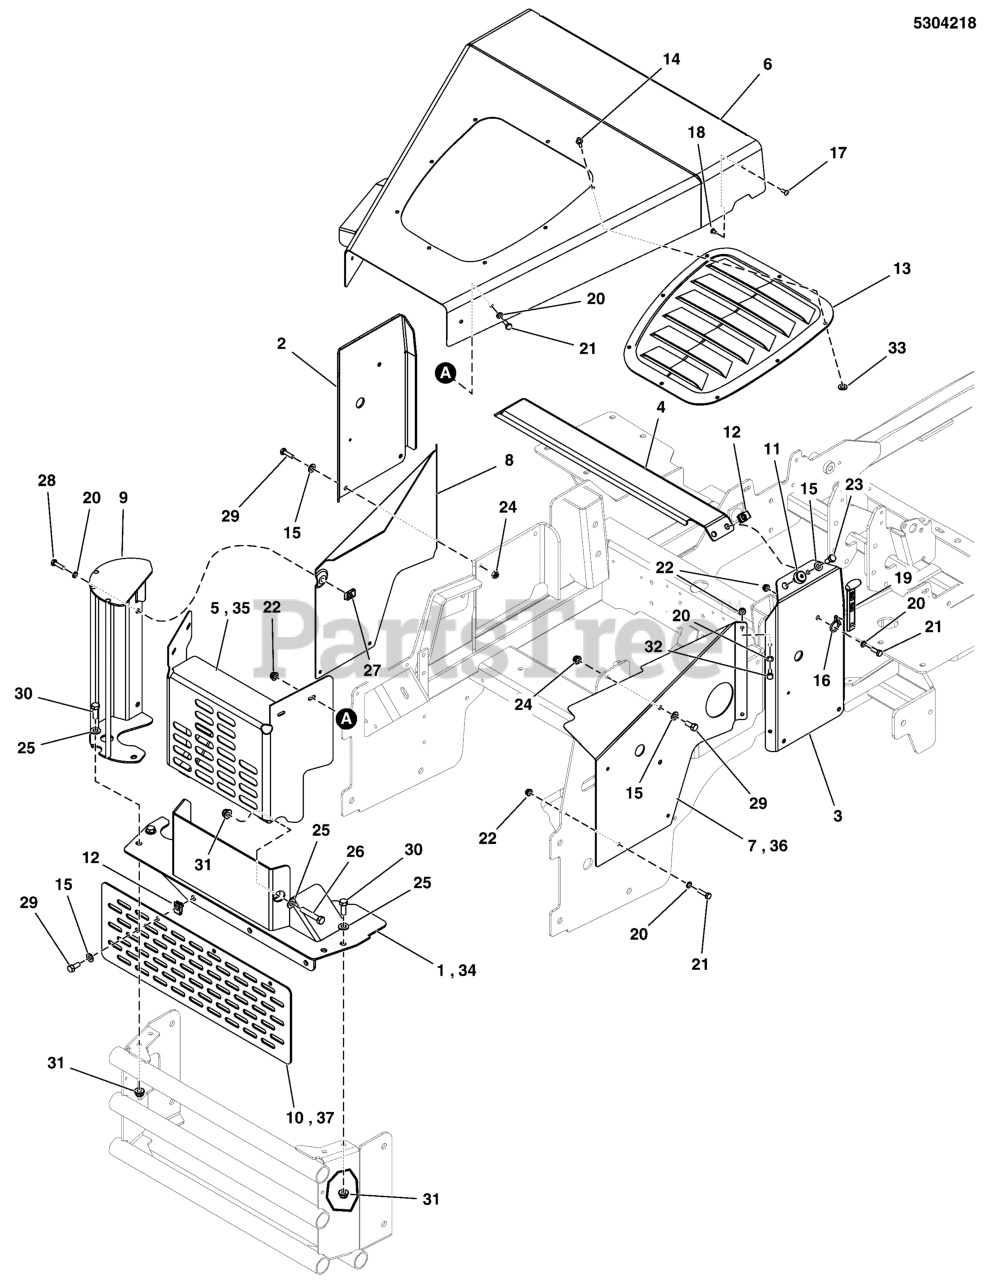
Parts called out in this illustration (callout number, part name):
1	WELD, HINGE MOUNT - RED
2	PLATE, LH HOOD SUPPORT, IS2600 - RED
3	PLATE, RH HOOD SUPPORT, IS2600 - RED
4	PLATE, CENTER HOOD SUPPORT, IS2600 - RED
5	WELD, ENGINE COVER, REAR - RED
6	WELD, HOOD, IS2600Z - RED
7	COVER, ENGINE SIDE, RH - RED
8	COVER, ENGINE SIDE, LH - RED
9	WELD, MUFFLER GUARD, IS2600Z
10	GUARD, REAR BELT
11	MNT, VBRTN, RBBR
12	BODY CLIP, 5/16-18-7GA MATERIAL
13	SCOOP, HOOD, OUTFRONT MOWER
14	POP RIVET, 3/16" X .575"(.251-.375GP)BLK
15	WASHER, 5/16" SAE
16	HOOK-.125DIA WIRE GR CAT STRAP YELLOW
17	BINDING POST #8-32X.500 INT THR BLK
18	SCREW-HEX SERR FLNG LK # 8-32X0.375 YEL
19	STRAP, HOOD, BLACK RUBBER
20	WASHER, 1/4 SAE
21	BOLT, 1/4-20 X 3/4 GD5 CZ
22	NUT, 1/4-20 HEX NYLOCK FLANGE
23	BOLT, 5/16-18 X 1 GD5 CZ
24	NUT, 5/16-18 HEX NYLOCK FLANGE
25	WASHER, 3/8 SAE
26	BOLT, 3/8-16 X 2, GD5, CZ
27	BODY CLIP, 1/4-20 X 1/2 DEEP
28	BOLT, 1/4-20 X 1" GD5 CZ
29	BOLT, 5/16-18 X 3/4 GD5
30	BOLT, 3/8-16 X 1" GD5 CZ
31	NUT, 3/8-16 HEX NYLOCK FLANGE
32	HHCS, 1/4-20 X 0.625, GR5, ZINC/CLEAR
33	WASHER, #10 SAE
34	WELD, HINGE MOUNT - RED
35	WELD, ENGINECOVER, REAR - RED
36	COVER, ENGINE SIDE, RH - RED
37	PLATE, GUARD, BUMPER - IS2600Z - RED
